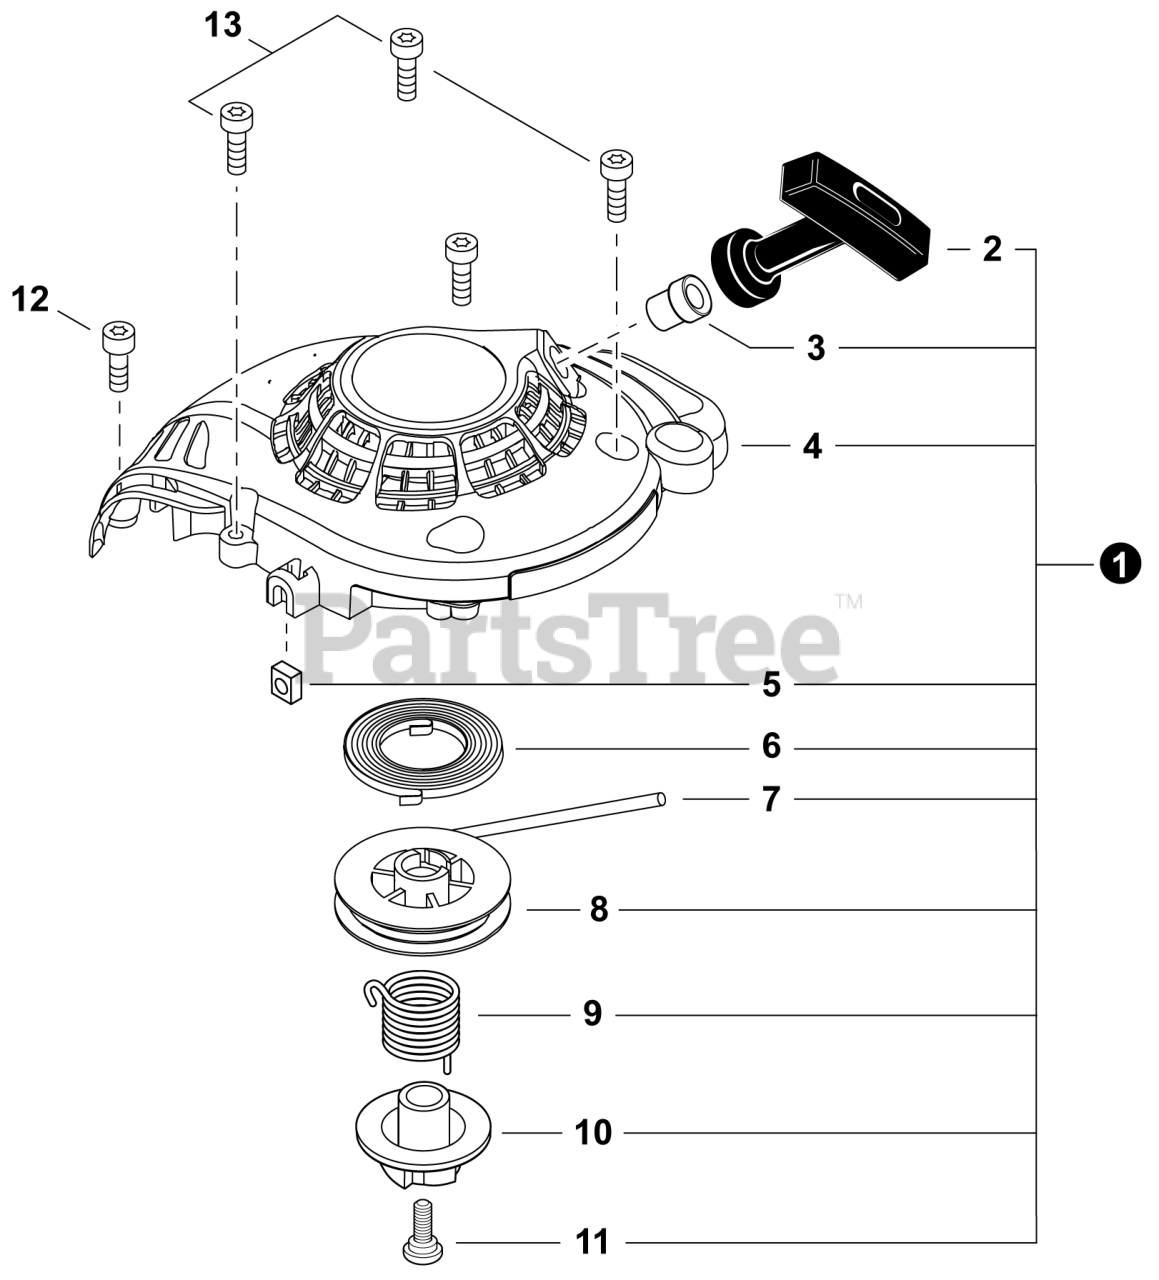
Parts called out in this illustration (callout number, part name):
1	STARTER ASSY, RECOIL
2	GRIP, STARTER
3	GUIDE, ROPE
4	CASE, STARTER
5	NUT - 5 - SQUARE
6	SPRING, RECOIL
7	ROPE, STARTER
8	REEL, ROPE
9	SPRING, TORSION
10	PLATE, CAM
11	SCREW 5
12	BOLT, TORX 4x16
13	BOLT, TORX 4x16
